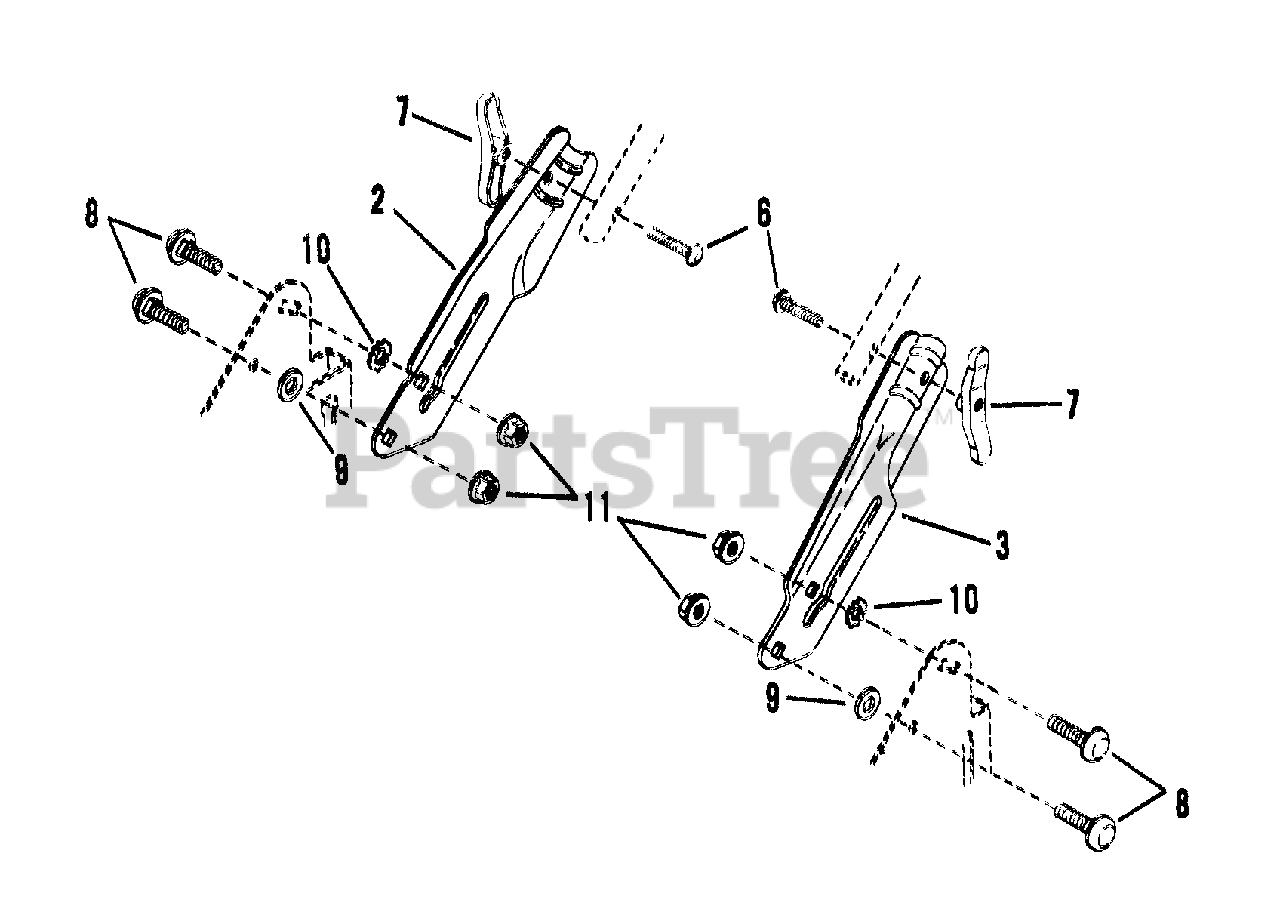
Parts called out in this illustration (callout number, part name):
2	HANDLE, Lower R. H.
3	HANDLE, Lower L. H.
6	BOLT, 1/4-20 x 1-3/4" Short Neck Carriage
7	NUT, 1/4-20 Wing
8	BOLT, 5/16-18 x 5/8" Short Neck Carriage
9	WASHER, 5/16 Flat
10	WASHER, 5/16 Internal-External Tooth Lock
11	NUT, 5/16-18 Hex Flange Lock
